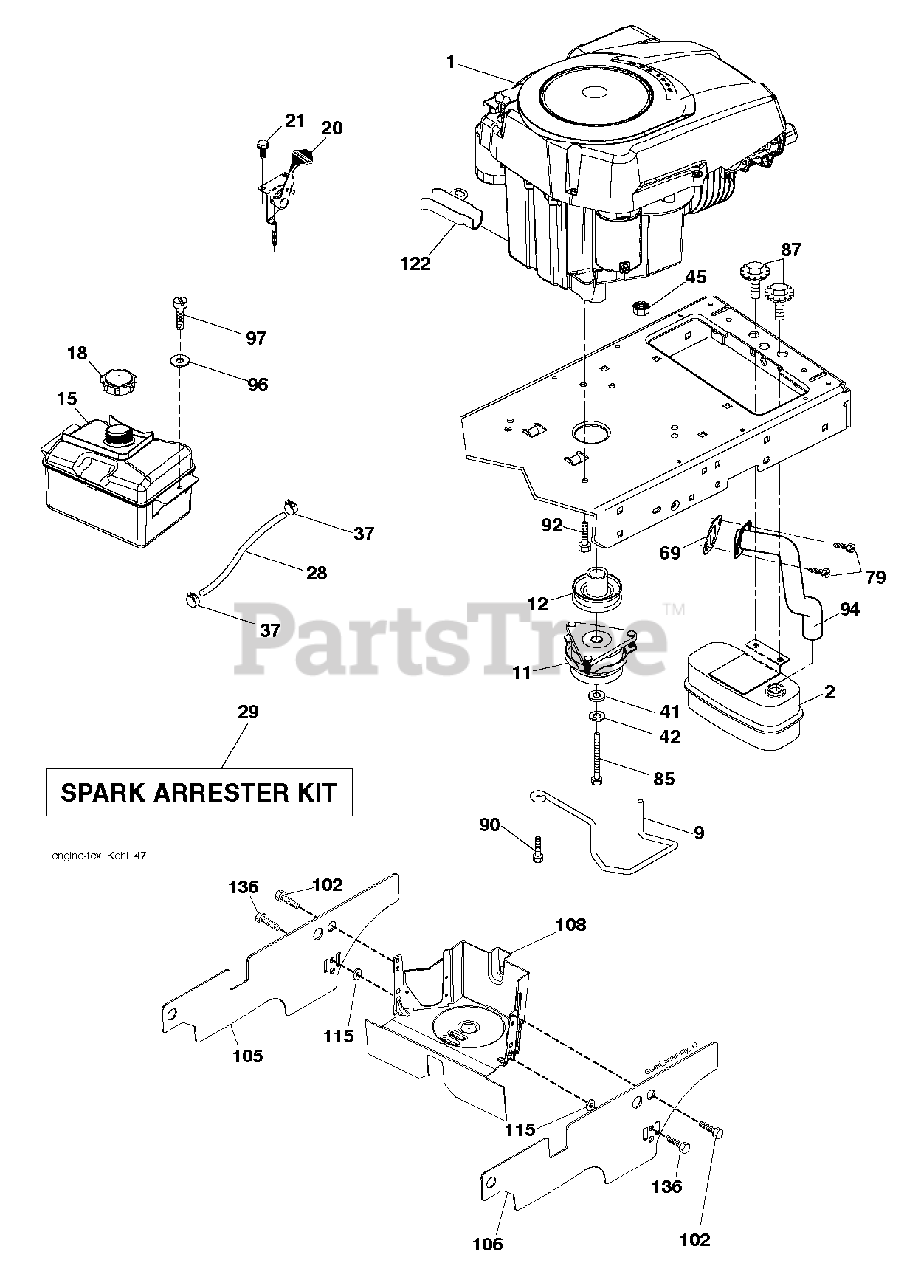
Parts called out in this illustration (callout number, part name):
2	MUFFLER.SINGLE.LRG.BRIGGS.KOHL
9	KEEPER BELT ENGINE
11	RB.CLUTCH.OGURA.4.4.PD
12	PULLEY.ENGINE.TUFFTORQ
15	FUEL.TANK.ASM.NON-EPA
18	CAP ASM.FUEL.2.25"FR.
20	CONTROL.TH/CK.C.
21	SCREW.#10 X 0.750.BOS
28	LINE.FUEL.20
29	KIT.SPARK ARRESTOR 794945 B&S
37	HOSE CLAMP
42	LOCKWASHER
45	NUT
69	GASKET.EXHAUST.KOHLER
79	SCREW.SOCKET HD.5/16-1
85	BOLT HEX 7/16-20X4-1/4"
87	BOLT, 5/16-18 X 1 3/4
90	SCREW 3/8-16X1
92	SCREW 3/8-16X1
94	TUBE.EXHAUST.KOHLER.COURAGE
97	SCREW HEXWSHR 1/4-20X3/4
102	SCREW
105	SHIELD.SIDE.LH.3842"TEX FRENCH
106	SHIELD.SIDE.RH.3842"TEX FRENCH
108	ENGINE COVER
115	PALNUT 1/4
122	EXTENSION DRAIN OIL
136	SCREW.1/4-20X5/8
